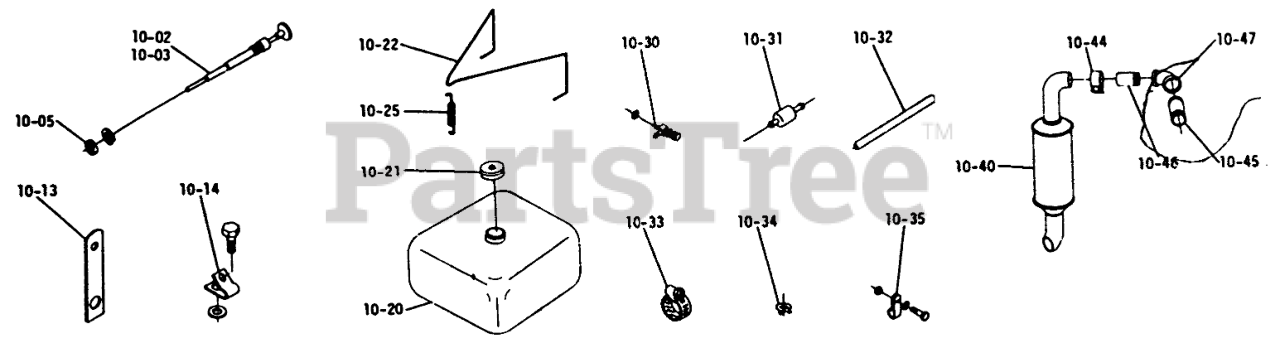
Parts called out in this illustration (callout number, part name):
10-05	RING NUT
10-14	THROTTLE CONTROL CLP
10-22	HOLD DOWN WIRE
10-30	S/A FUEL VALVE
10-45	Nipple 1" x 1 1/2
10-47	Elbow 90 X 1
